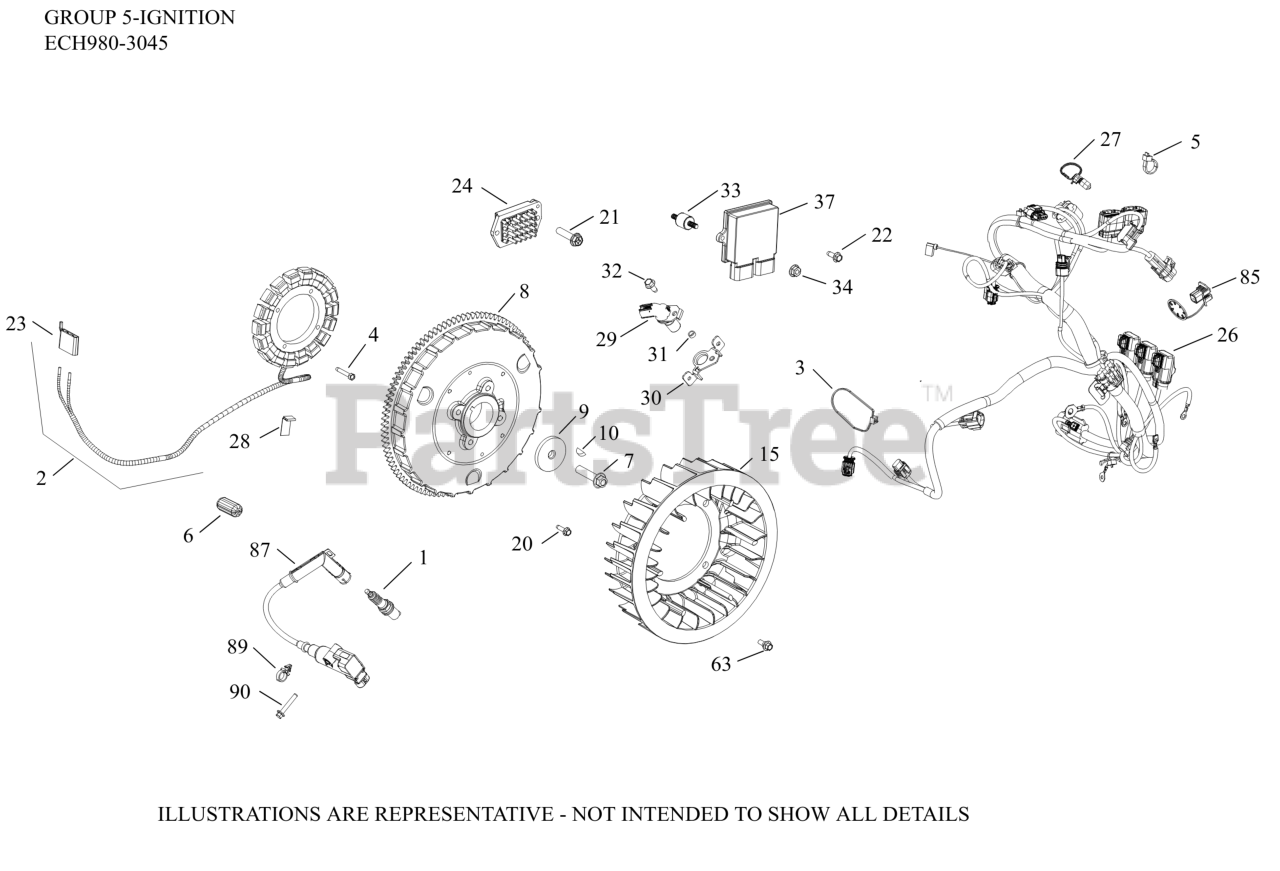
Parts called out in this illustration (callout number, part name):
1	PLUG, SPARK
2	KIT, 25 AMP STATOR ASSY.
3	TIE, CABLE
4	SCREW, THREAD FORMING
5	TIE, WIRE
6	SLEEVE, EMI SUPPRESSION
7	SCREW, FLG M10X1.5X45-USE 25 086 361-S
8	FLYWHEEL ASSEMBLY
9	WASHER, FLAT 13/32"
10	KEY, 3/16" X 5/8"
15	FAN-(#6215706S)
20	SCREW, THREAD FORMING
21	SCREW, HEX FLANGE HI-LO
22	SCREW, THREAD FORMING
23	CONNECTOR
24	REGULATOR, RECT (20-30AMP, FW W/OVP)
26	HARNESS, WIRING (8-BAY EFI HORIZONTAL)
27	TIE, WIRE
28	CLIP, BLOWER HOUSING
29	SENSOR, SPEED
30	BRACKET, CRANK SENSOR
32	SCREW, THREAD FORMING
33	ISOLATOR, VIBRATION STUD
34	NUT, FLG M5X.8
37	MODULE, ECU ECH 980-USE 62 584 61-S
63	BOLT, SHOULDER
85	CAP, CONNECTOR (4-WAY, BLACK)
87	COIL, IGNITION - EFI (RFI/EMC)
90	SCREW, HEX FLANGE
